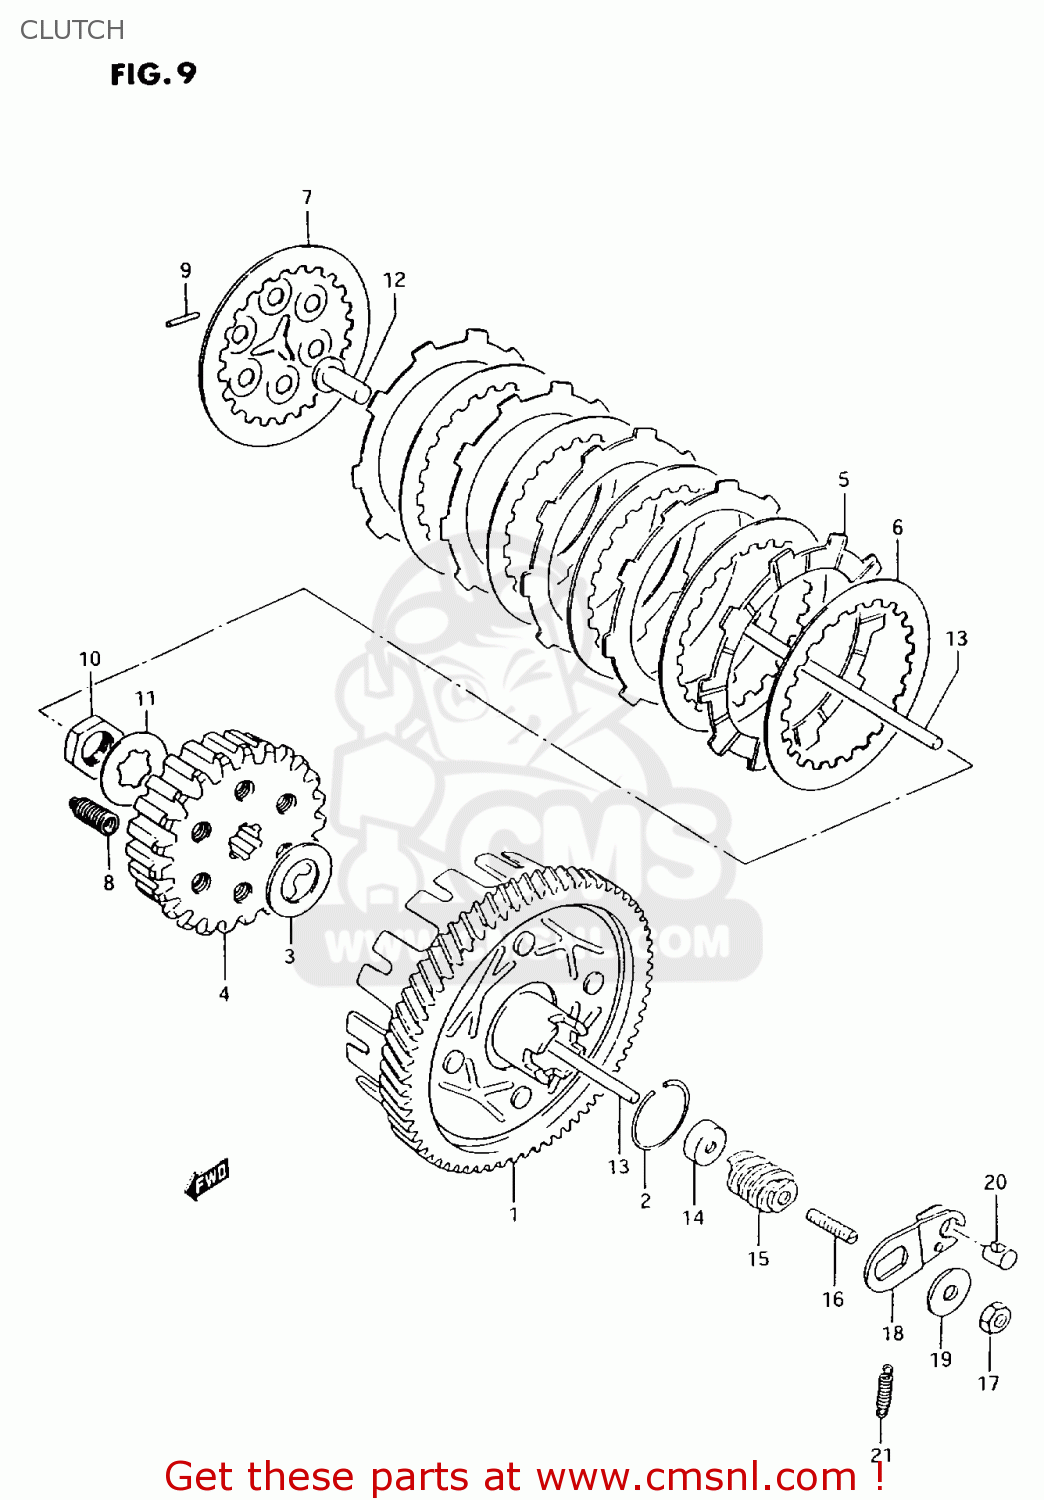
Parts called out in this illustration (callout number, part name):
1	GEAR ASSY,PRI DRIVEN
2	CLIP
3	WASHER
4	HUB,CLUTCH SLEEVE
5	PLATE,CLUTCH DRIVE (NA (NAS)
6	PLATE,CLUTCH DRIVEN (NAS)
7	PLATE,CLUTCH PRESSURE
8	SPRING
9	PIN(2.5X19.8)
10	NUT
11	WASHER,LOCK
12	PIECE,CLUTCH PUSH
13	ROD,CLUTCH PUSH
14	SEAL,OIL(5.5X16X8)
15	SCREW,CLUTCH RELEASE
16	SCREW(6X25)
17	NUT
18	ARM,CLUTCH RELEASE
19	WASHER(6.5X20X1.6)
20	HOOK,CLUTCH RELEASE SCREW ARM
21	SPRING
